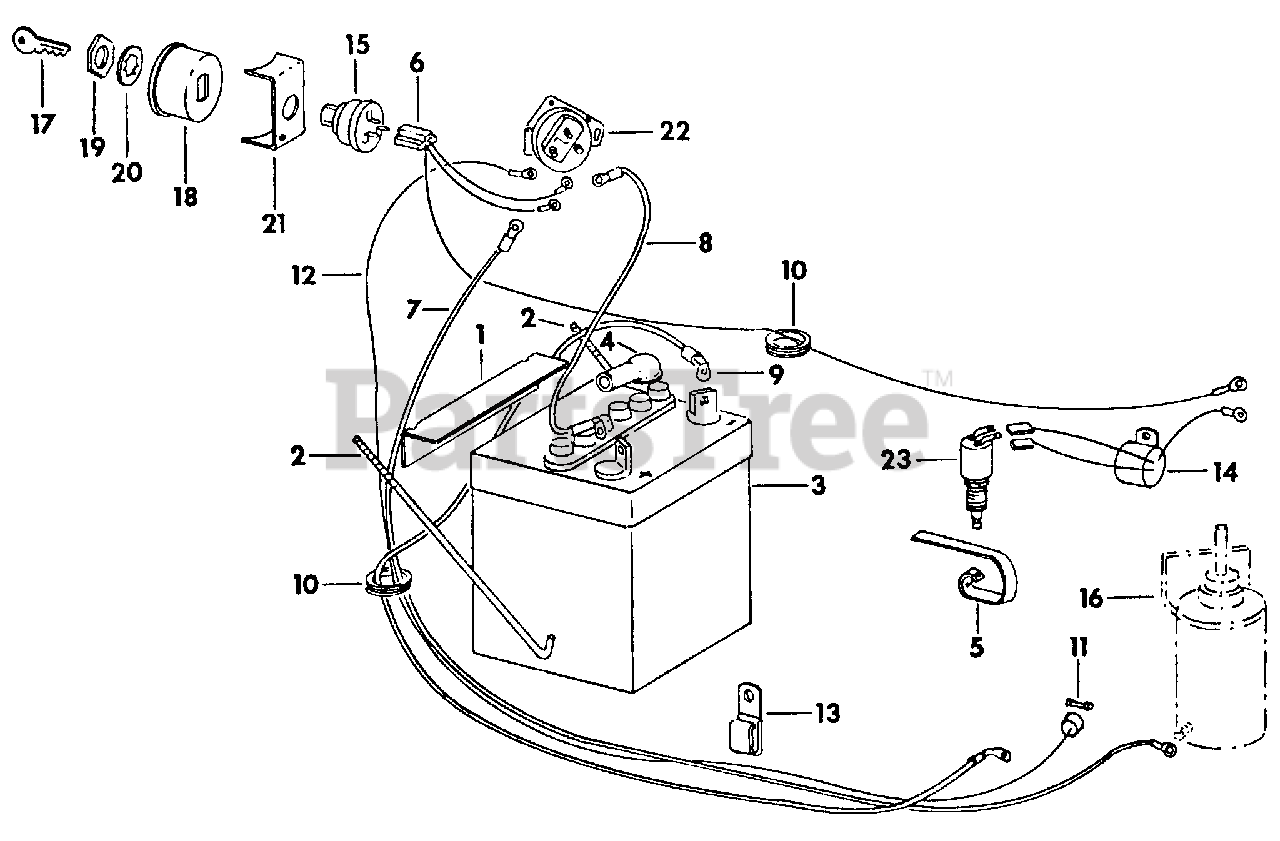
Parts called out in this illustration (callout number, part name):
1	Clamp, Battery Hold Down
2	Bolt, Battery Hold Down
3	Battery, IH Low Maintenance, 12 Volt
4	Cover, Battery Terminal
5	Spring, Neutral Start
6	Harness Assy, Cable
7	Cable Assy, Magnetic Switch to Starter
8	Cable Assy, Battery to Magnetic Switch
9	Cable Assy, Battery to Ground
12	Cable Assy, Fuse to Magnetic Switch
13	Clip, Cable Harness
14	Module Assy, Control
15	Switch, Ignition & Starting
16	Starting Motor
17	Key, Ignition Switch
18	Socket, Ignition Switch
19	Nut, Ignition Switch
20	Washer, Ignition Switch
21	Retainer, Ignition Switch
22	Switch, Magnetic
23	Switch Assy, Neutral Starting
